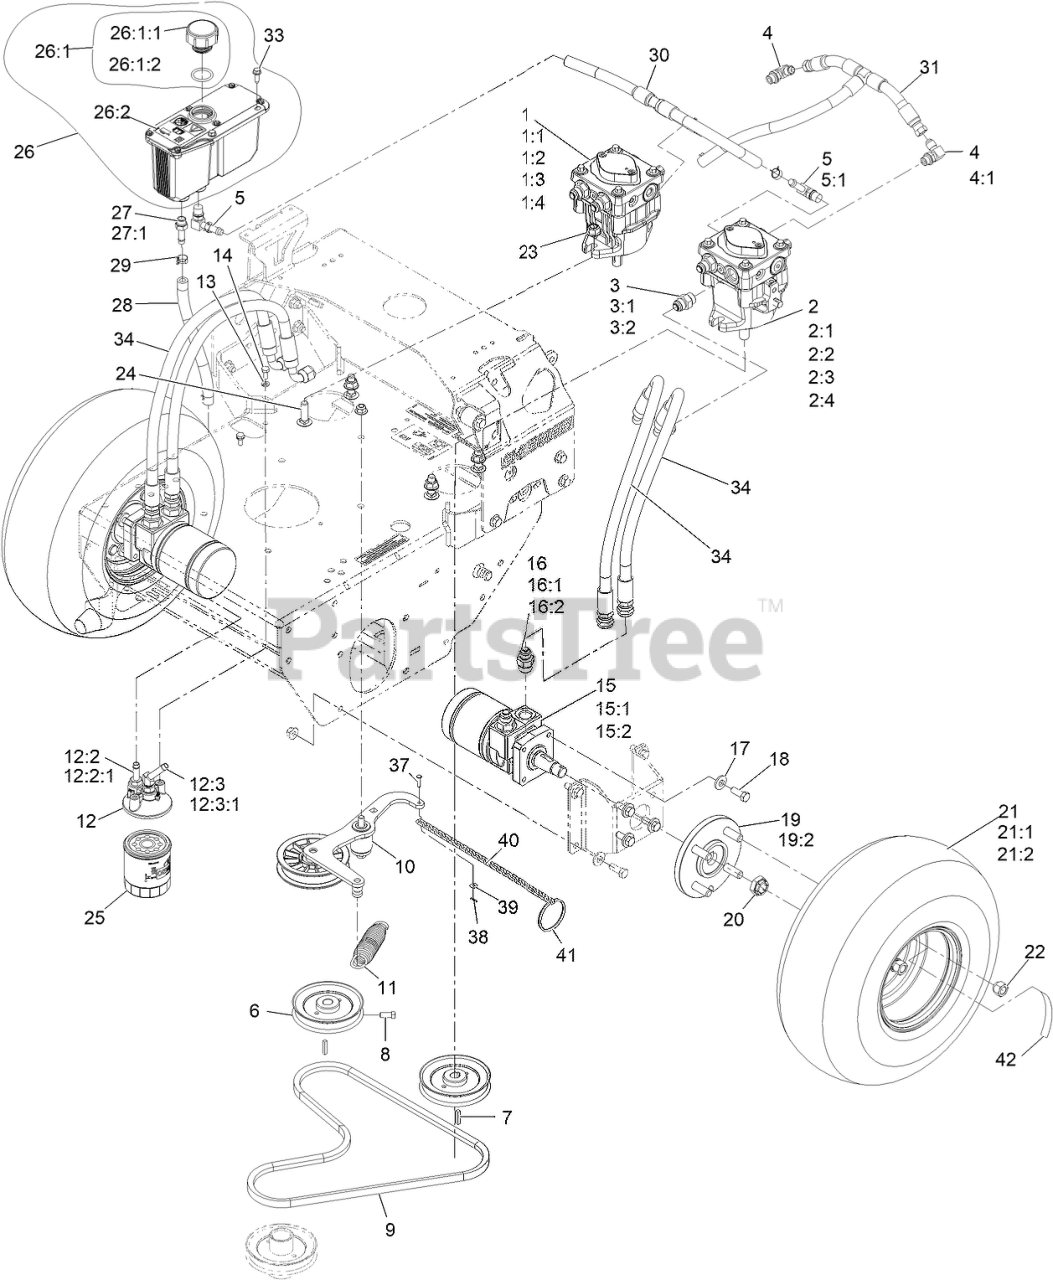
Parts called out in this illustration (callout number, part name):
1	RH HYD PUMP ASM
1:1	INPUT SHAFT KIT
1:2	BEARING-THRUST
1:3	CYLINDER BLOCK KIT
1:4	SEAL OVERHAUL KIT
2	LH HYD PUMP ASM
2:1	INPUT SHAFT KIT
2:2	BEARING-THRUST
2:3	CYLINDER BLOCK KIT
2:4	SEAL OVERHAUL KIT
3	FITTING-STRAIGHT
4	FITTING-ELBOW, 90 DEG
4:1	O-RING
5	FITTING-ELBOW, 90
5:1	O-RING
6	SHEAVE ASM
8	SCREW-SET, SQH
9	BELT
10	ASM, PUMP IDLER
11	SPRING-EXTENSION
12	ASM, FILTER HEAD
12:2	ADAPTER-STRAIGHT
12:2:1	O-RING
12:3	FITTING-BARBED, 45 DEG
12:3:1	O-RING
13	WASHER-LOCK
14	SCREW-HH
15	HYD MOTOR ASM
15:1	SEAL KIT
15:2	BEARING AND SEAL KIT
16	FITTING-STRAIGHT
16:1	O-RING
17	WASHER-BELLEVILLE
18	SCREW-HH
19	WHEEL HUB ASM
19:2	STUD-WHEEL
20	NUT-LOCK
21	WHEEL AND TIRE ASM
21:1	TIRE-TURFMASTER
21:2	RIM-WHEEL
22	NUT-LUG
23	NUT-HF, NI
24	BOLT-CARR
25	FILTER-25 MICRON, BI-DIRECTIONAL
26:1	Reservoir-HYD
26:1:1	Cap-Reservoir, HYD
26:2	DECAL-WARNING
27	ADAPTER-STRAIGHT
27:1	O-RING
28	HOSE-CHARGE
29	CLAMP-HOSE
30	HOSE-CASE DRAIN
31	HOSE-CHARGE
33	SCREW-HWH, THREAD ROLL
34	HYD HOSE ASM
37	PIN-CLEVIS
38	PIN-HAIR
39	WASHER-PLAIN
40	CHAIN-LINK, TWIST
41	RING-SPLIT
42	DECAL-TORQUE WHEEL LUG-HU
